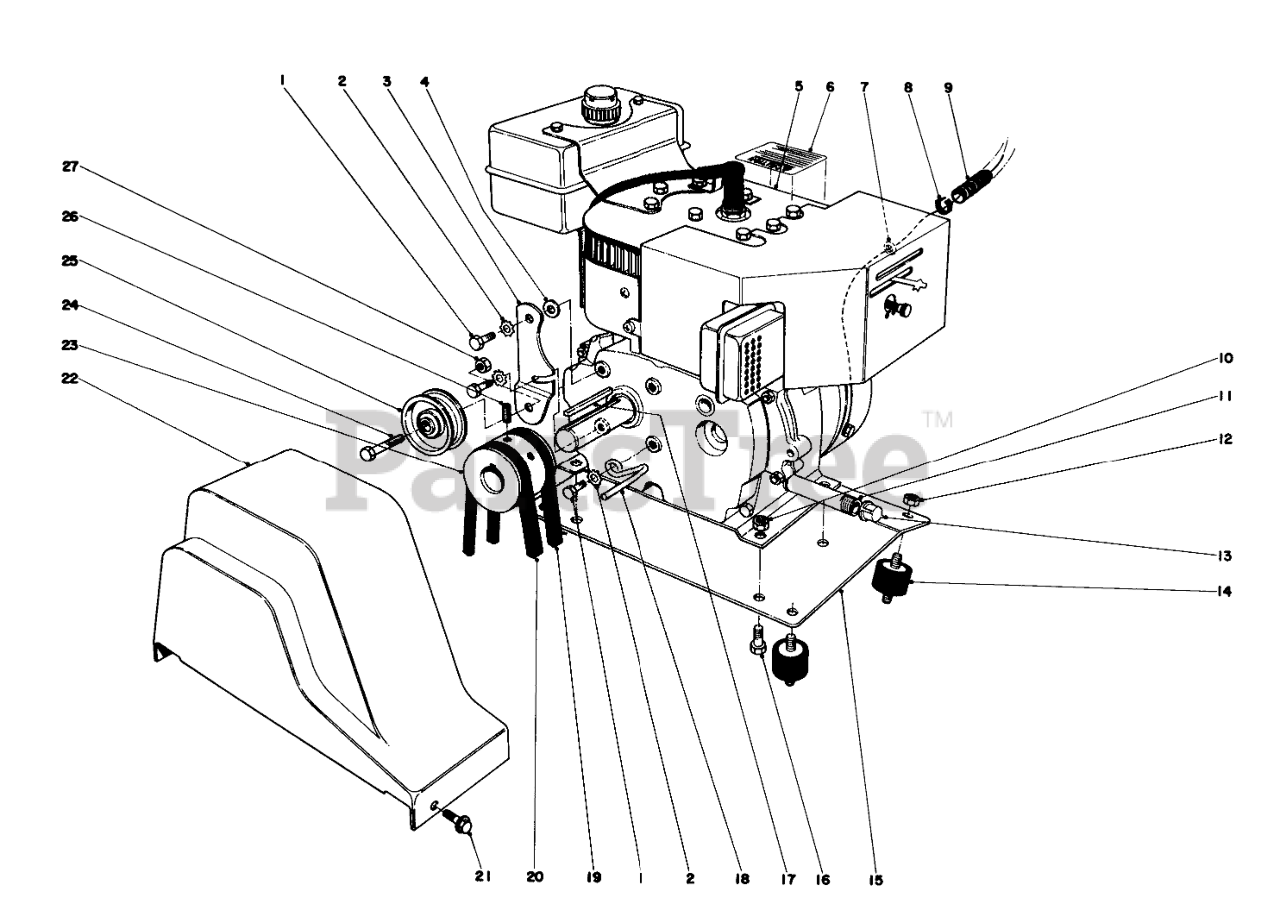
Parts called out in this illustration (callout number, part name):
1	SCREW-HH
2	WASHER-LOCK
3	ENGINE IDLER ARM
4	WASHER-PLAIN
5	Engine (Model No. 31625)
6	Decal Instruction
7	GROMMET
8	RING FITTING
9	Cover Harness
10	NUT-LOCK, CONE
11	NIPPLE-PIPE
12	NUT-KEPS
13	CAP-PIPE
14	Engine Mount
15	Engine Mounting Plate
16	SCREW-HH
18	BELT RETAINER
19	V-BELT
20	V-Belt
21	SCREW-HWH
22	BELT GUARD
23	ENGINE PULLEY
24	SCREW-HH
25	PULLEY-IDLER
26	Screw-Set
27	NUT-HEX
